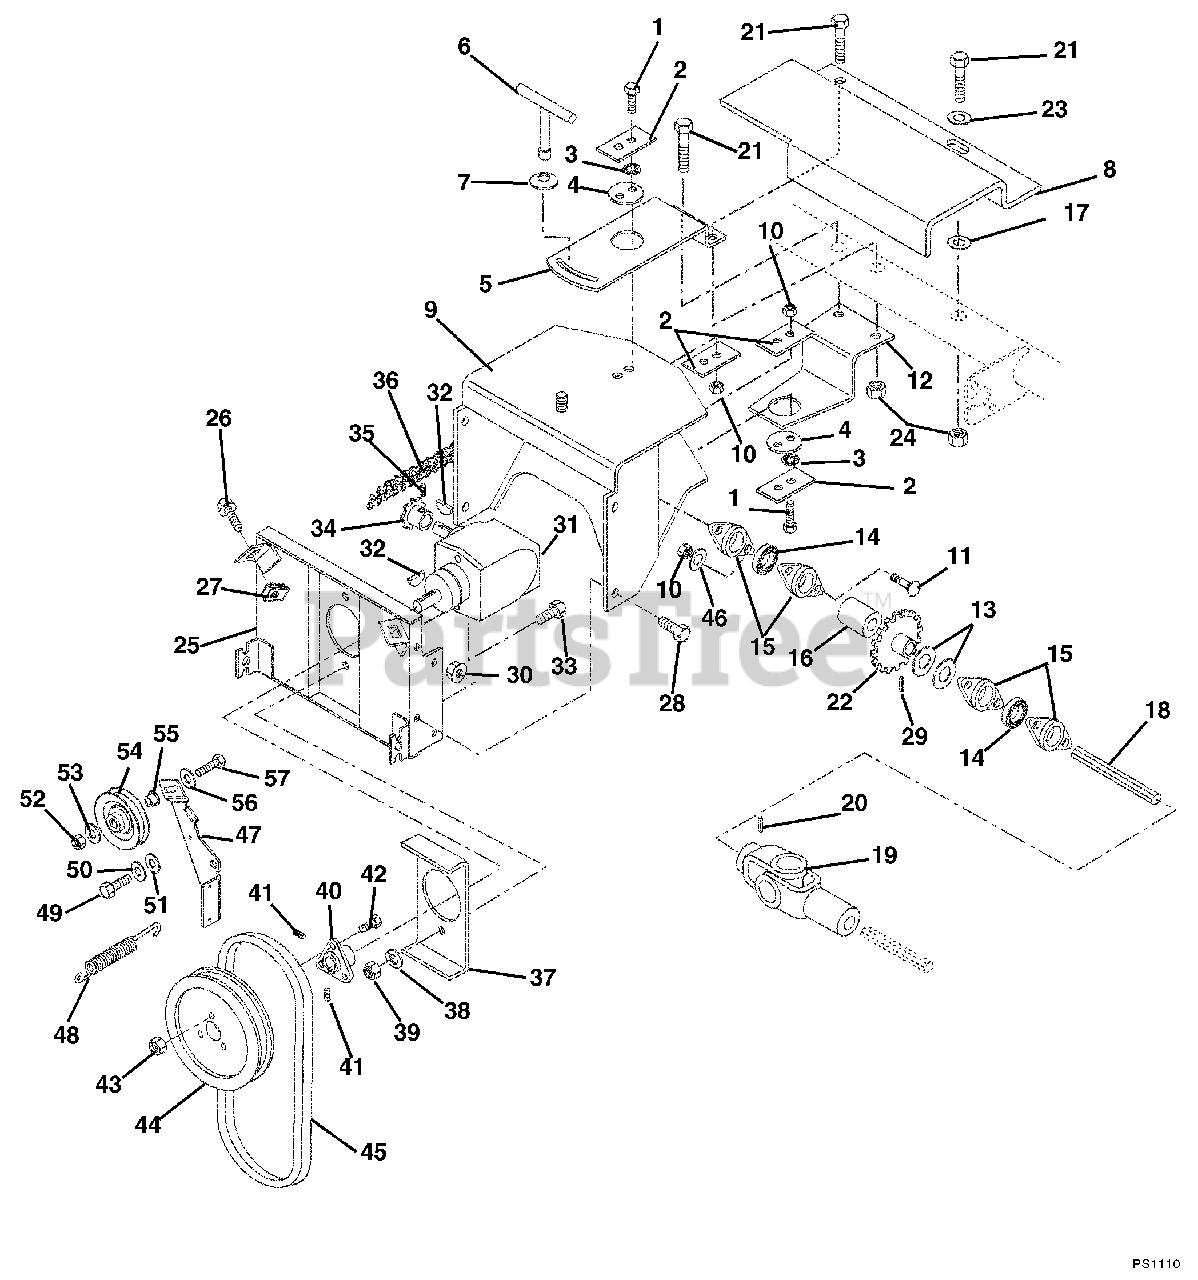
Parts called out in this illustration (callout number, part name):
1	@BLT-HEX .31-18X1.25 GR5 YWZC
2	RETAINER
3	@WSHR-LK-EXT.326X.599X.031YWZC
4	PIVOT CENTER
5	PLATE, TOP MOUNT
6	T-LOCK HANDLE
7	WASHER, CUPPED SERRATED, .375
8	GUARD, SHAFT
9	FRAME, ADAPTOR
10	@NUT-LK-CTR .31-18 YWZC
11	@BLT-RDHDSQNK .31-18X.75 G5YZ
12	PLATE, BOTTOM MOUNT
13	WSHR-FL-STL 1.015X1.500X.125
14	BRG-BALL .884HEXX52MMX1.07
15	BEARING FLANGE
16	SPACER 1.006X1.307X.500
17	WSHR-FL-STL .390X.88X.18 YWZC
19	JOINT, UNIVERSAL
20	PIN-ROLL .188X1.50
21	@BLT-HEX .38-16X3.25 GR5 YWZC
22	SPROCKET
23	@WSHR-FL-STL.406X.812X.065 YWZ
24	@NUT-LK-CTR .38-16 YWZC
25	PLATE, MOUNTING-BROOM
26	BLT-SERHFWH .38-16X.75 YWZC
27	NUT-RETNR .38-16 TINRMAN
28	@BLT-HEX .38-16X.75 GR5 YWZC
29	PIN-ROLL .188X1.75
30	@NUT-LK-CTR .38-16 YWZC
31	GEAR BOX ASSEMBLY
32	KEY-WDRF .188X.75X.313 SAE 9
33	@BLT-HEX .38-16X1.25 GR5 YWZC
34	SPROCKET
35	SCR-SET .25-20X.38 SKHCUPNL OH
36	CHAIN
37	PLATE, STIFFENER
38	@WSHR-LK .38X.094 REG YWZC
39	@NUT-HEX .38-16 YWZC
40	HUB ASSEMBLY
41	SCR-SET .31-18X.38 SKHCUPDL
42	BLT-SERRDHD SL .31-18X.75 YZ
43	@NUT-SPNLK-FLG .312-18 YWZC
44	PLY-V 9.0 X 1.25 3BLT
45	V-BELT, 4L-RAW EDGE
46	@WSHR-FL-STL.38X.875X.083 YWZC
47	ARM, AUGER/BRAKE-HIGH W/LINING
48	SG-TENS .062X.56X8.0 WLD 11
49	@BLT-HEX .31-18X.75 GR5 YWZC
50	WSHR-LK .312X.097 HVY YWZC
51	WSHR-FL-STL .328X1.0X.094 YWZC
52	@NUT-LK-CTR .31-18 YWZC
53	@WSHR-FL-STL.344X.688X.065YWZC
54	IDLER
55	SPCR, BRG .315X.50X.688X.281
56	@WSHR-FL-STL.38X.875X.083 YWZC
57	@BLT-HEX .31-18X1.25 GR5 YWZC
